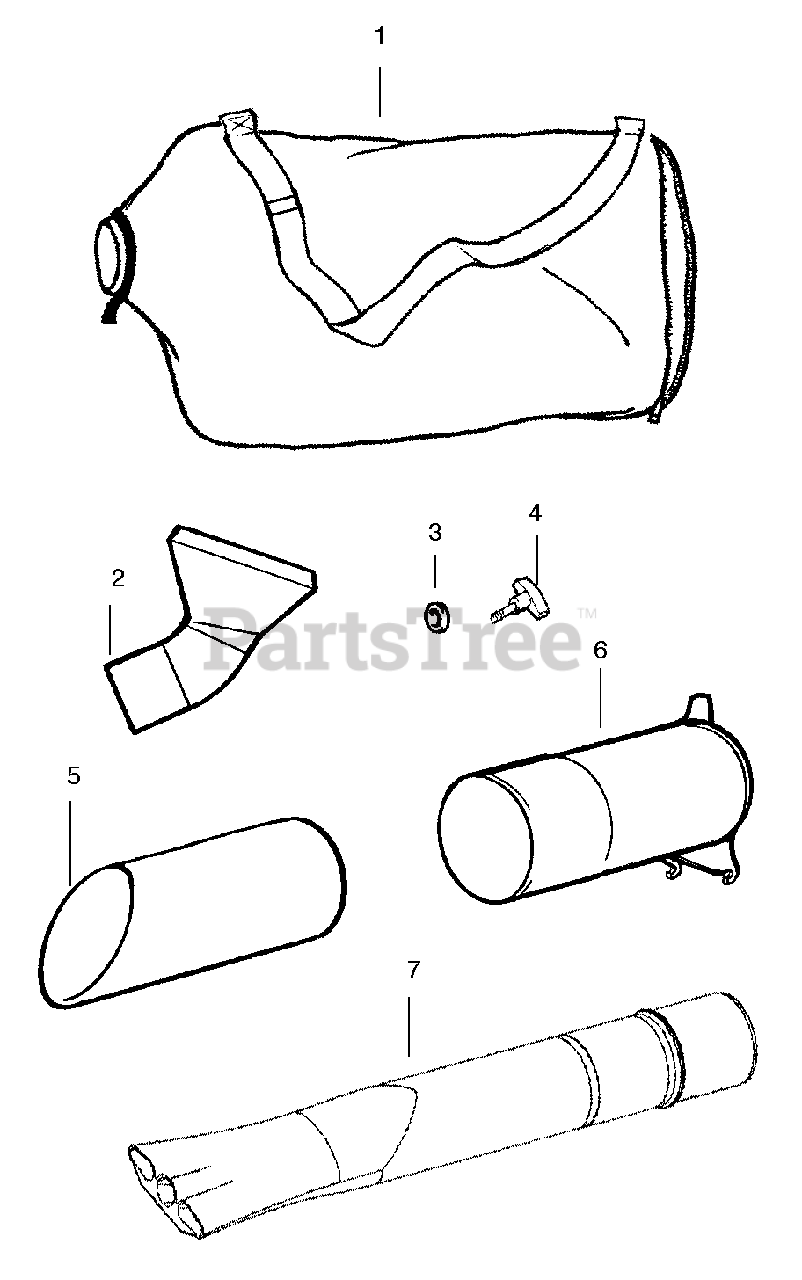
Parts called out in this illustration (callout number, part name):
1	Assy-Vac. Bag w/strap
2	Tube-Elbow Vac
3	Retainer-Vac Tube Knob
5	Tube-Lower Vac
6	Tube-Upper Vac
7	Tube-Blower
